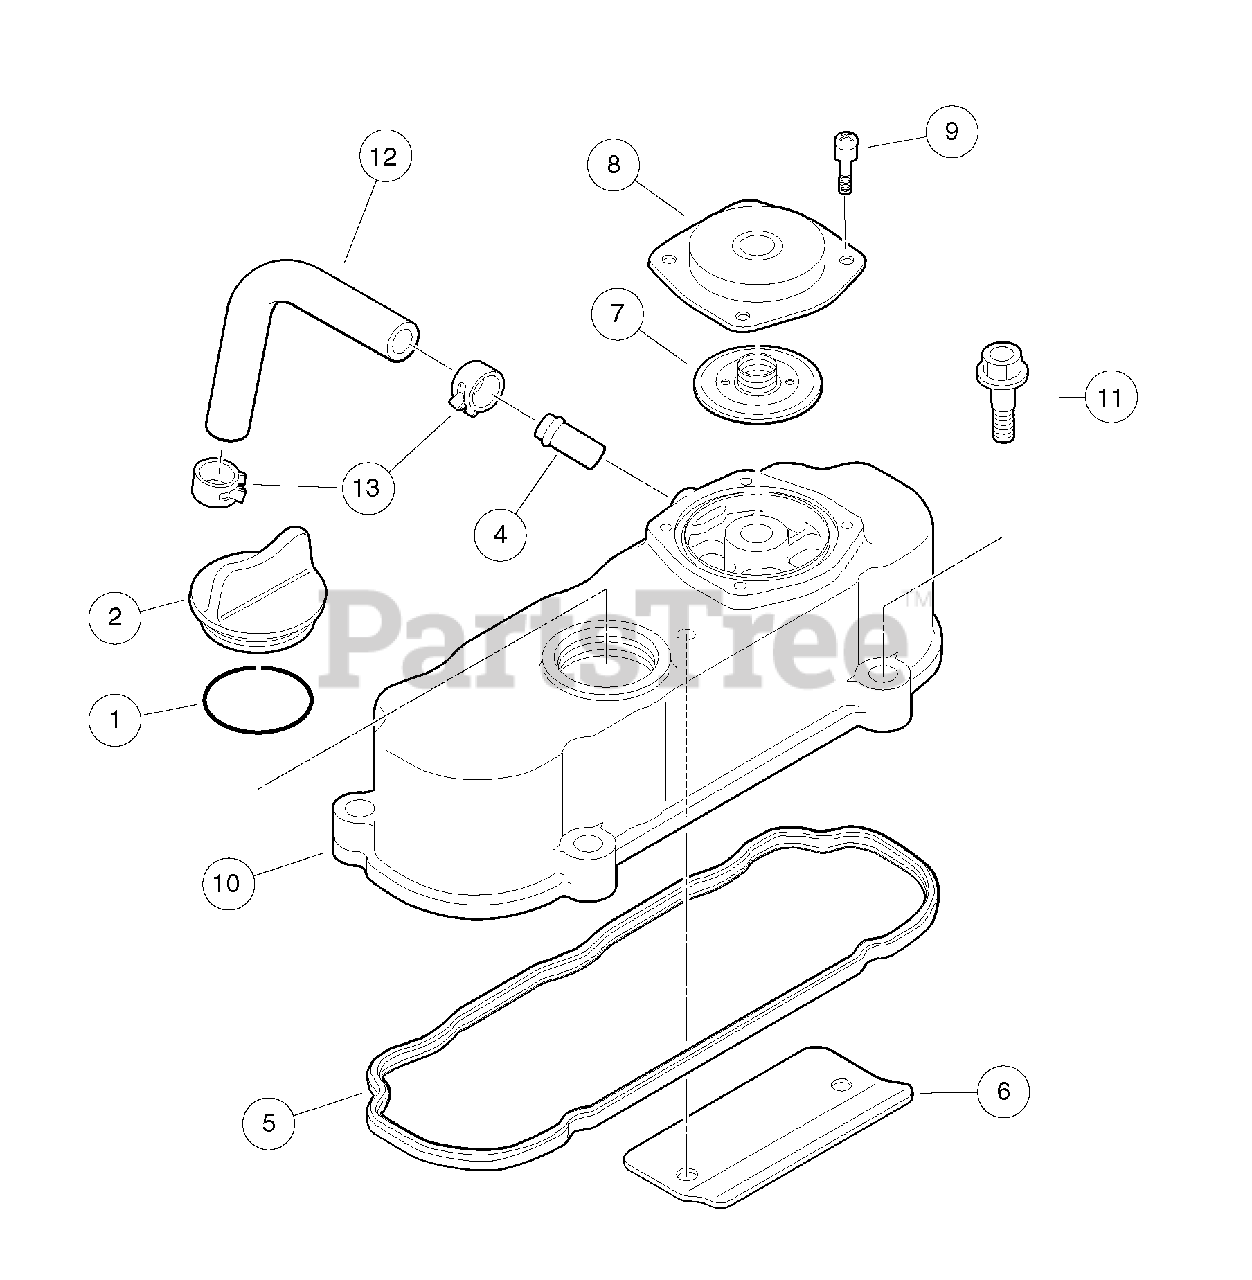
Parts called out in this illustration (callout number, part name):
1	O Ring, 30 X 36
2	Plug, Oil Filler
3	Assembly, Cylinder Head Cover
4	Pipe, Water Return, D722
5	Gasket, Cylinder Head Cover
6	Shield, Breather
7	Valve, Breather
8	Cover, Breather
9	Screw, Breather
10	Cover, Cylinder Head
11	Bolt, Cylinder Head Cover
12	Tube, Breather
13	Clamp, Breather Tube
